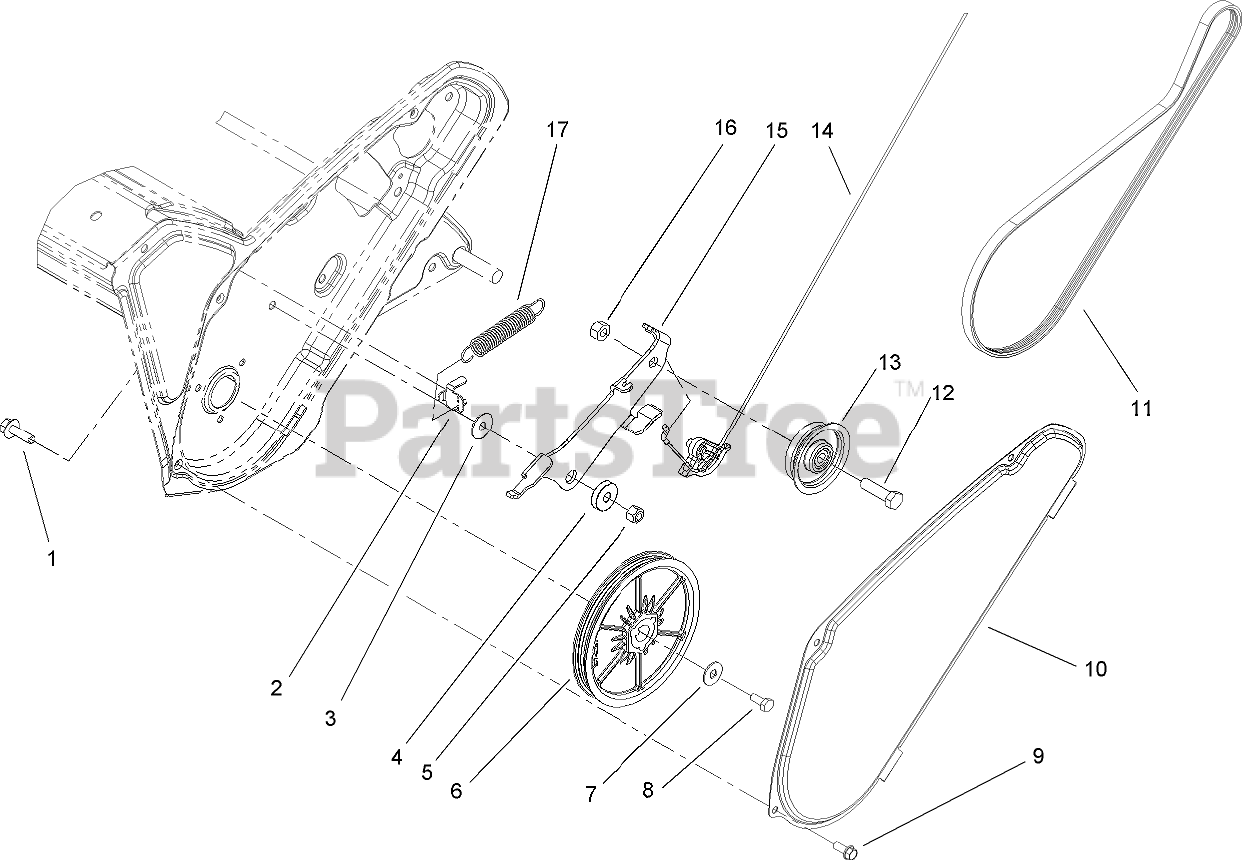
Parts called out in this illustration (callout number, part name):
1	SCREW-HHF
2	CLIP-SPRING, BRAKE
3	WASHER
4	BUSHING-PIVOT
5	NUT-LOCK, NI
6	ROTOR PULLEY ASM
7	WASHER-BELLEVILLE
8	SCREW-HH
9	SCREW-HWH
10	COVER-BELT
11	BELT-DRIVE
12	SCREW-HH
13	PULLEY-IDLER
14	CABLE-CLUTCH
15	ARM-IDLER
16	NUT-LOCK, CONE
17	SPRING-EXTENSION
